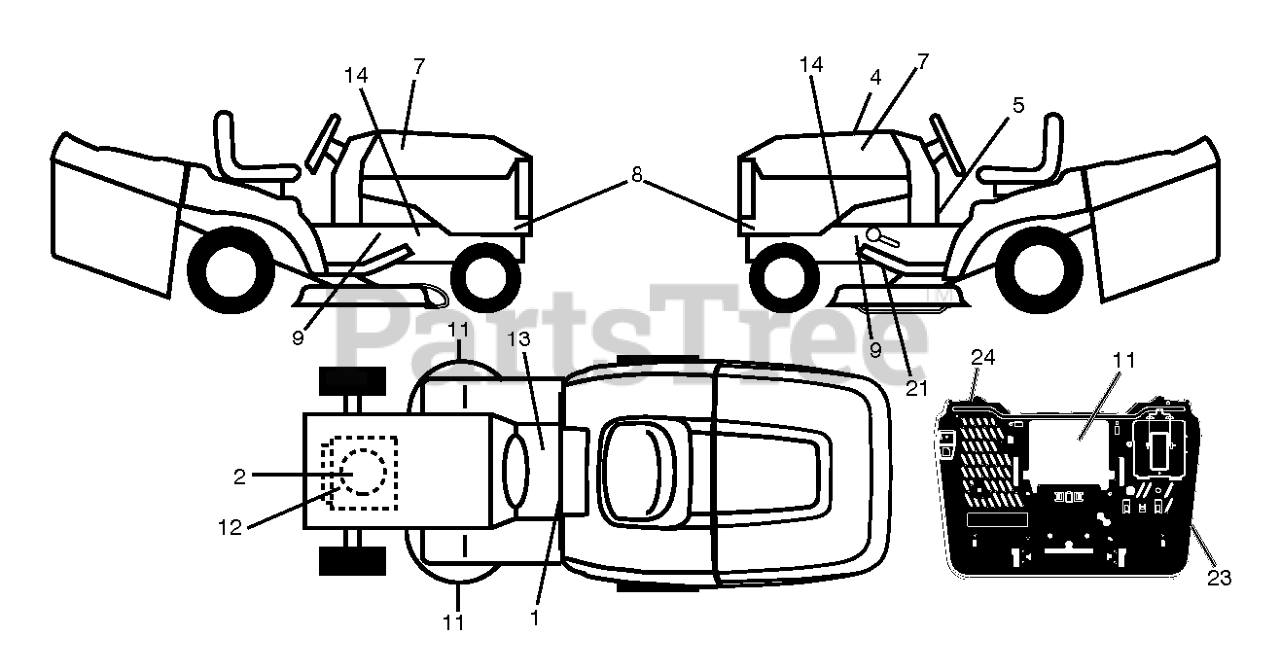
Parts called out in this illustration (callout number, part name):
1	DECAL.WARNING.COMBINED.T/CRD
2	DECAL.ENGINE.WARNING
4	DECAL.RPL.BSM40.ENDUR.TCRD.97E
5	DECAL.INSTRUCTION.MLCH/BG.VERT
7	DECAL.BADGE.170MM.TEXTLOGO.
8	DECAL.TRACTOR.SDPNL.HUSQ
9	DECAL.WARNING.SERVCE/FIRE
11	DECAL.CUTFINGER.CE.02
12	DECAL.ENG.BS.656.ENDUR.382292
13	DECAL.FWD/REV.PEDAL.SYMBOL
14	DECAL.CHASSIS.HOT.MUFFLER
21	DECAL DECAL V-BELT 97 CM CRD
23	DECAL DECAL.BYPASS.BACKPLATESI
24	DECAL DECAL.WARNING.COMBINED.T
